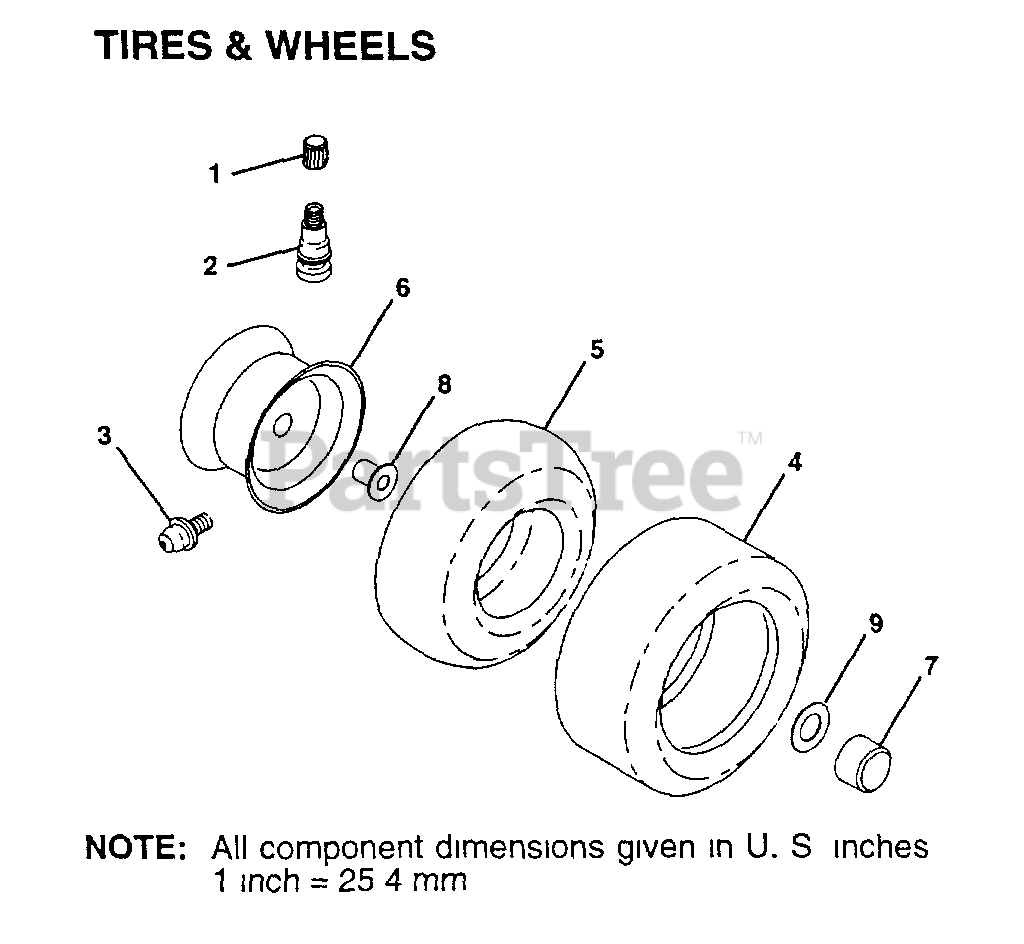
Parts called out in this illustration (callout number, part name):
1	VALVE CAP
2	VALVE STEM LT
3	FITTING LT
5	TUBE.5.3/4.5/6
6	"RIM.FRONT.6"".YEL"
7	HUB CAP
8	"FLANGE, BEARING"
9	WASHER
